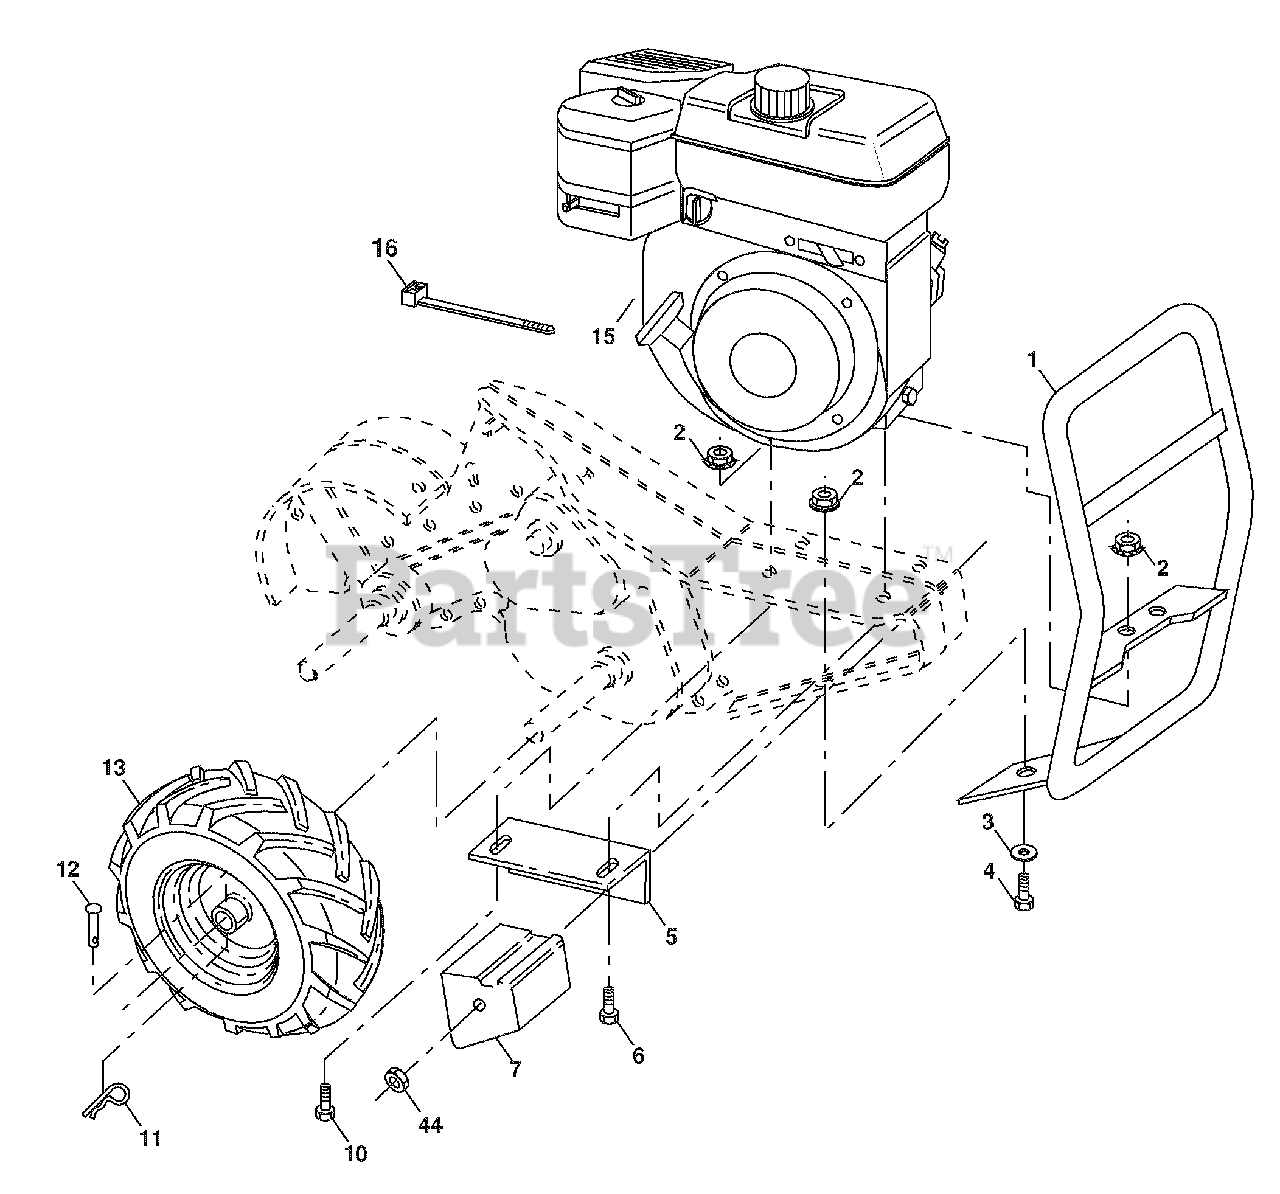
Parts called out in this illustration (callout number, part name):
1	Bumper Asm.
2	Locknut, Hex, Flange 5/16-18
3	Washer 11/32 x 11/16 x 16 Ga.
4	Bolt 5/16-18 x 3/4
5	Bracket, Reinforcement R.H.
6	Bolt 5/16-18 x 1-3/4
7	Counter Weight, R.H.
10	Bolt, Hex 5/16-18 x 1-1/2
11	Clip, Hairpin
12	Rivet, Drilled
16	Tie, Cable
44	Nut Keps Hex 3/8-16 unc
